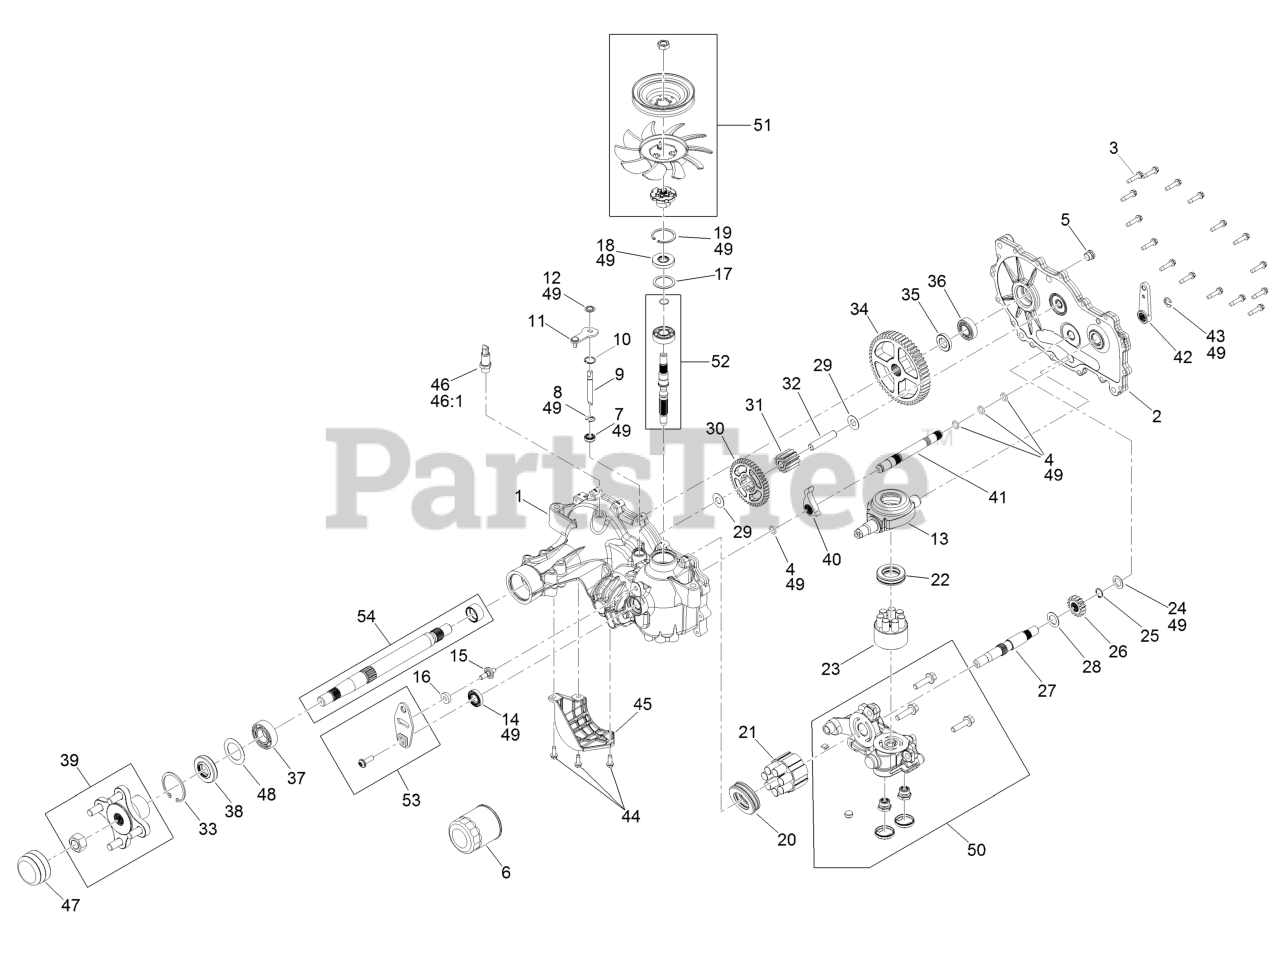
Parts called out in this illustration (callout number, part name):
1	MAIN HOUSING KIT
2	RH SIDE COVER KIT
3	SCREW-HHF
5	PLUG-THREAD, STRAIGHT
6	ELEMENT-OIL FILTER, HYD
7	SEAL-LIP
8	RING-RETAINING, EXTERNAL
9	ROD-BYPASS
10	RING-RETAINING, INTERNAL
12	RING-RETAINING, EXTERNAL
13	SWASHPLATE-TRUNNION
14	SEAL-LIP
16	PUCK-FRICTION
18	SEAL-LIP
19	RING-RETAINING
20	BEARING-THRUST
21	MOTOR CYLINDER BLOCK KIT
22	BEARING-THRUST
23	PUMP BLOCK ASM
24	WASHER-FLAT
25	RING-RETAINING
26	GEAR-16T
27	SHAFT-MOTOR
30	GEAR-43T
31	GEAR-11T
32	PIN-JACKSHAFT
33	RING-RETAINING
34	GEAR-54T
36	BEARING-BALL
37	BEARING-BALL
39	HUB KIT
40	PAWL-BRAKE
41	SHAFT-BRAKE, INBOARD
42	HANDLE-BRAKE
43	RING-RETAINING, EXT
45	GUARD-FILTER, RH
46	ADAPTER-STRAIGHT
46:1	O-RING
47	COVER-NUT, AXLE
49	SEAL KIT
50	RH CENTER SECTION KIT
51	FAN PULLEY KIT
52	INPUT SHAFT KIT
53	CONTROL ARM KIT
54	AXLE SHAFT KIT
